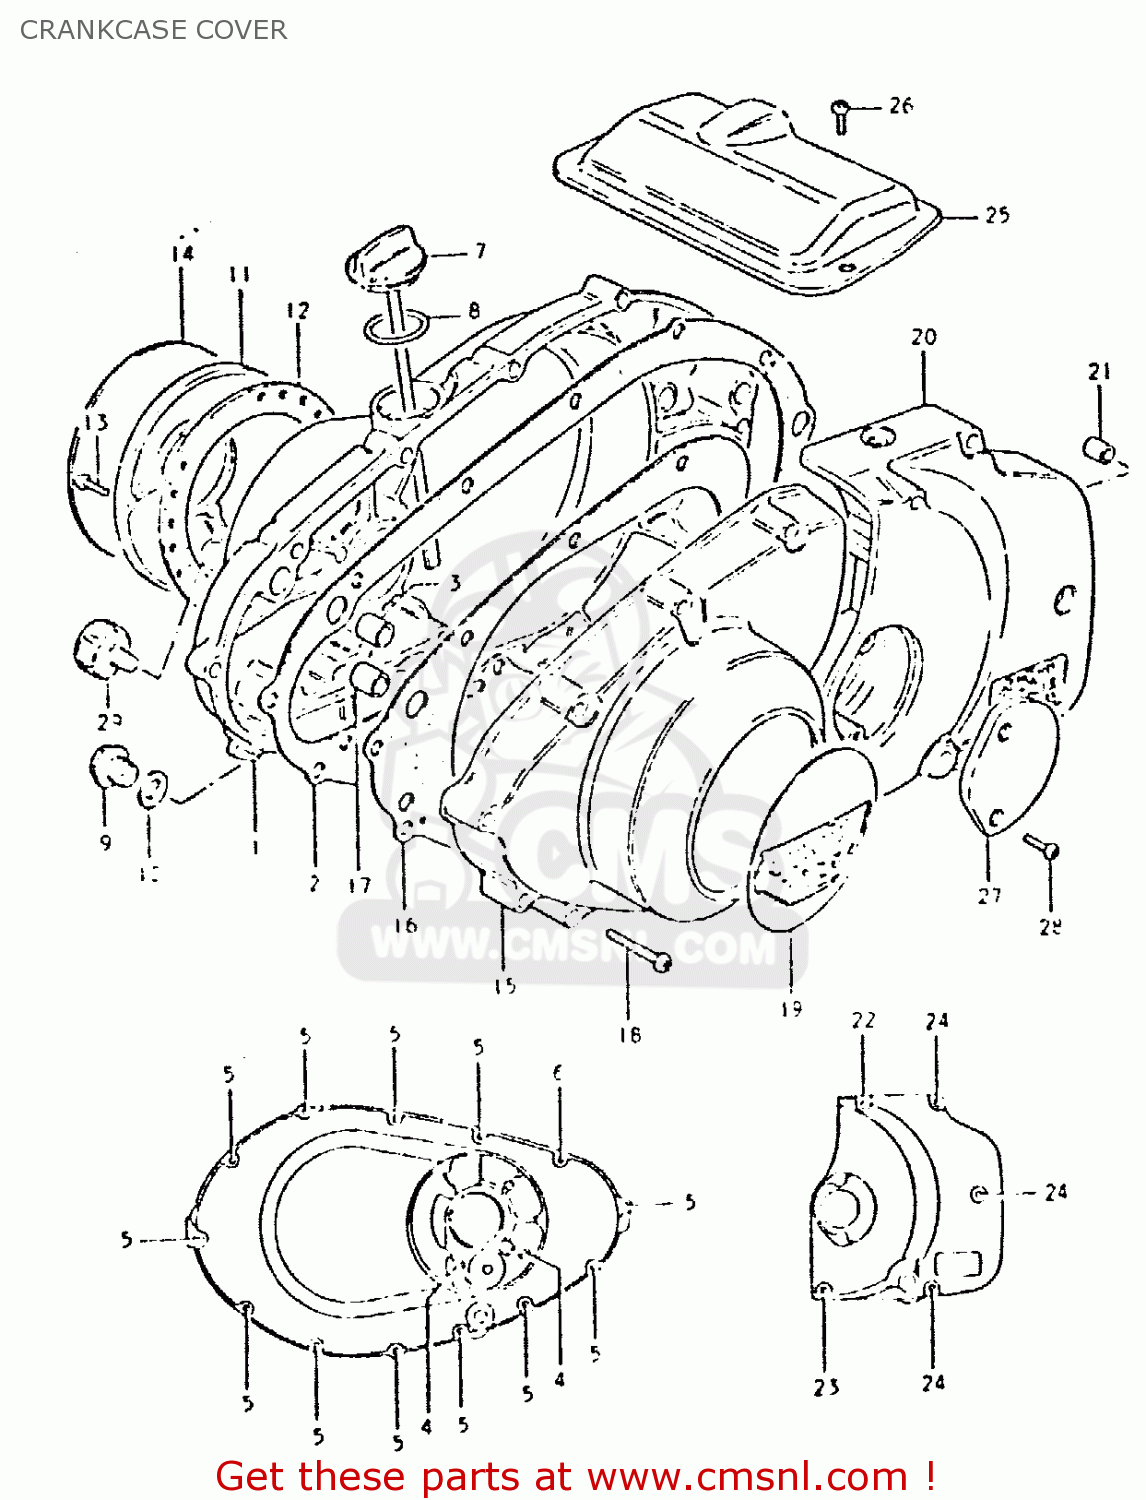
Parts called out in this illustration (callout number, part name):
1	COVER,CLUTCH
2	GASKET,CLUTCH COVER (MCA)
3	PIN
4	SCREW
5	SCREW (6X35)
6	SCREW
7	GAUGE,OIL LEVEL
8	O-RING
9	PLUG (14X12)
10	GASKET(14X19.2X2) (NAS)
11	COVER,CONTACT BREAKER
12	GASKET,CONTACT BREAKER COVER (NAS)
13	SCREW
14	EMBLEM
15	COVER
16	GASKET,MAGNETO COVER (MCA)
17	PIN
18	SCREW (6X35)
19	EMBLEM
20	COVER,SPROCKET
21	PIN
22	SCREW 6X65
23	SCREW
24	SCREW
25	COVER,STARTER MOTOR
26	SCREW
27	CAP,CLUTCH RELEASE ADJUST
28	SCREW 5X12
29	SWITCH ASSEMBLY
